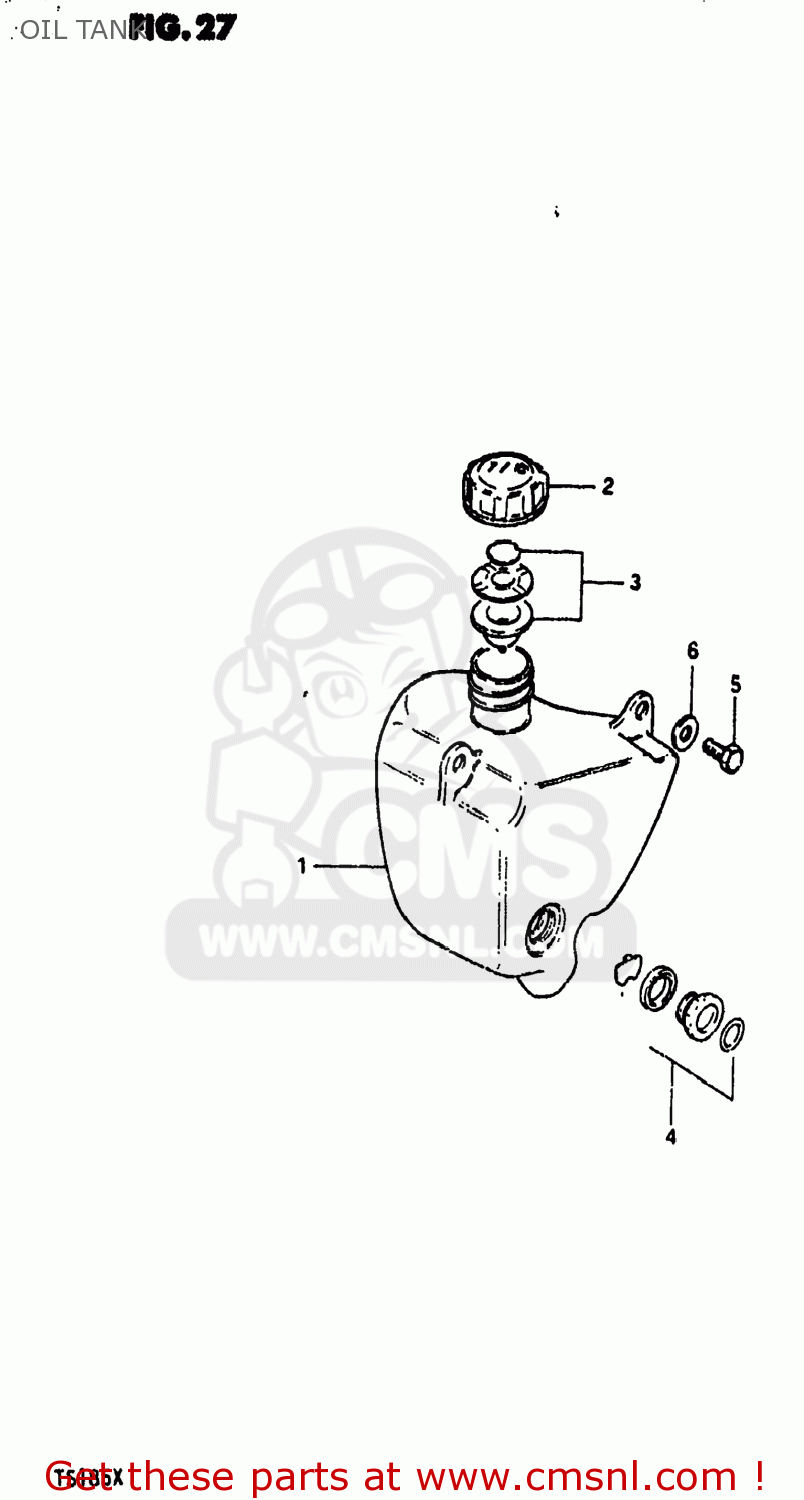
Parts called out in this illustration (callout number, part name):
1	TANK,OIL
2	CAP,OIL TANK
3	GASKET SET (NAS)
4	LENS SET,OIL LEVEL
5	BOLT, UPPER
6	WASHER
